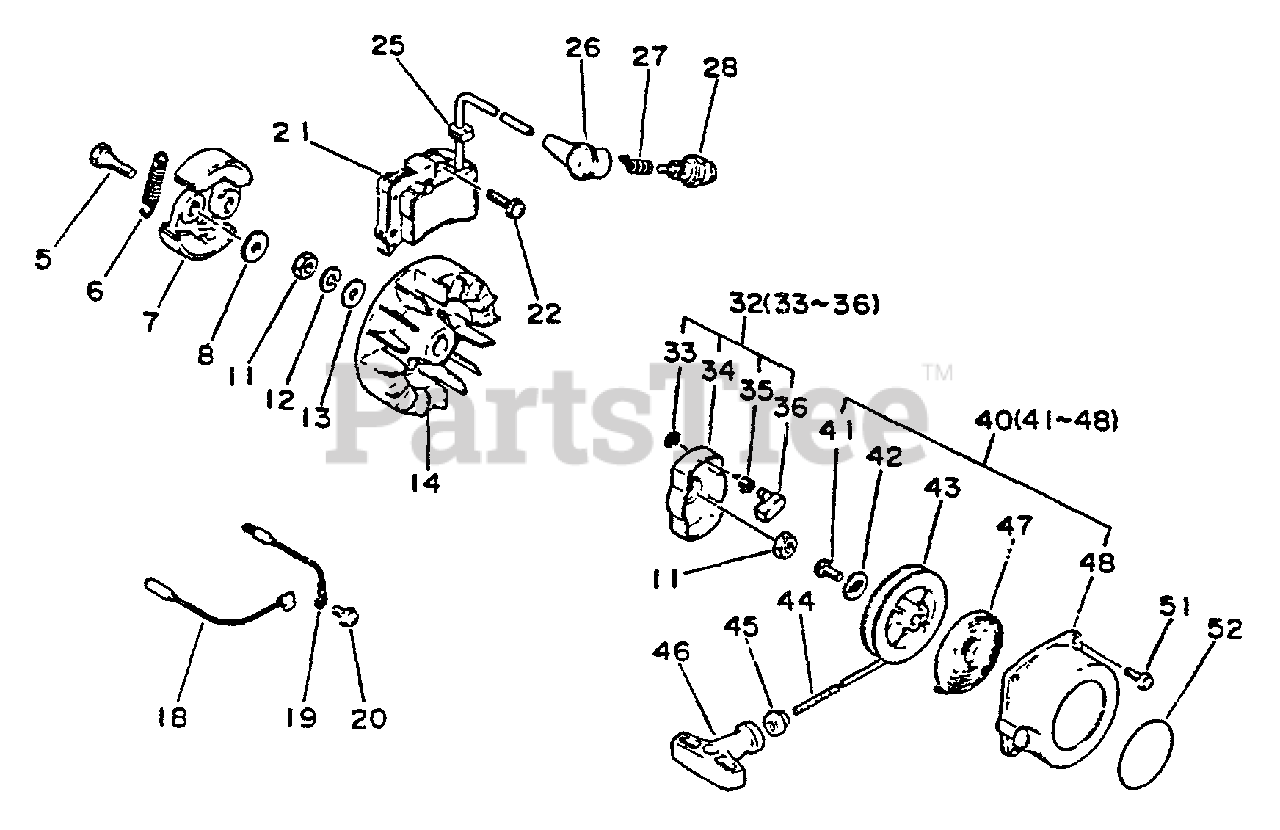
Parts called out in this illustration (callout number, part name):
5	BOLT, CLUTCH
6	SPRING, CLUTCH
7	SHOE, CLUTCH
8	WASHER 6.2×19×1.0
11	NUT 8×1.25
12	WASHER, SPRING 5
13	WASHER 8.5×16×1.2
14	FLYWHEEL
18	LEAD - GROUND
19	LEAD - GROUND L= 115
20	SCREW 5×10
21	COIL, IGNITION
22	SCREW 5×20
26	CAP, SPARK PLUG
27	TERMINAL, SPARK PLUG
28	SPARK PLUG - BPM7A
28	SPARK PLUG - BPMR7A
32	PAWL ASSY, STARTER
33	RING, RETAINING - 6
34	CATCHER, PAWL
35	SPRING, RETURN
36	PAWL, STARTER
40	STARTER ASSY
42	WASHER
43	REEL, ROPE
44	ROPE, STARTER 3.5×850
45	GUIDE, ROPE
46	GRIP, STARTER
47	SPRING, RECOIL
48	CASE, STARTER
51	SCREW 5×14
52	LABEL - ECHO
